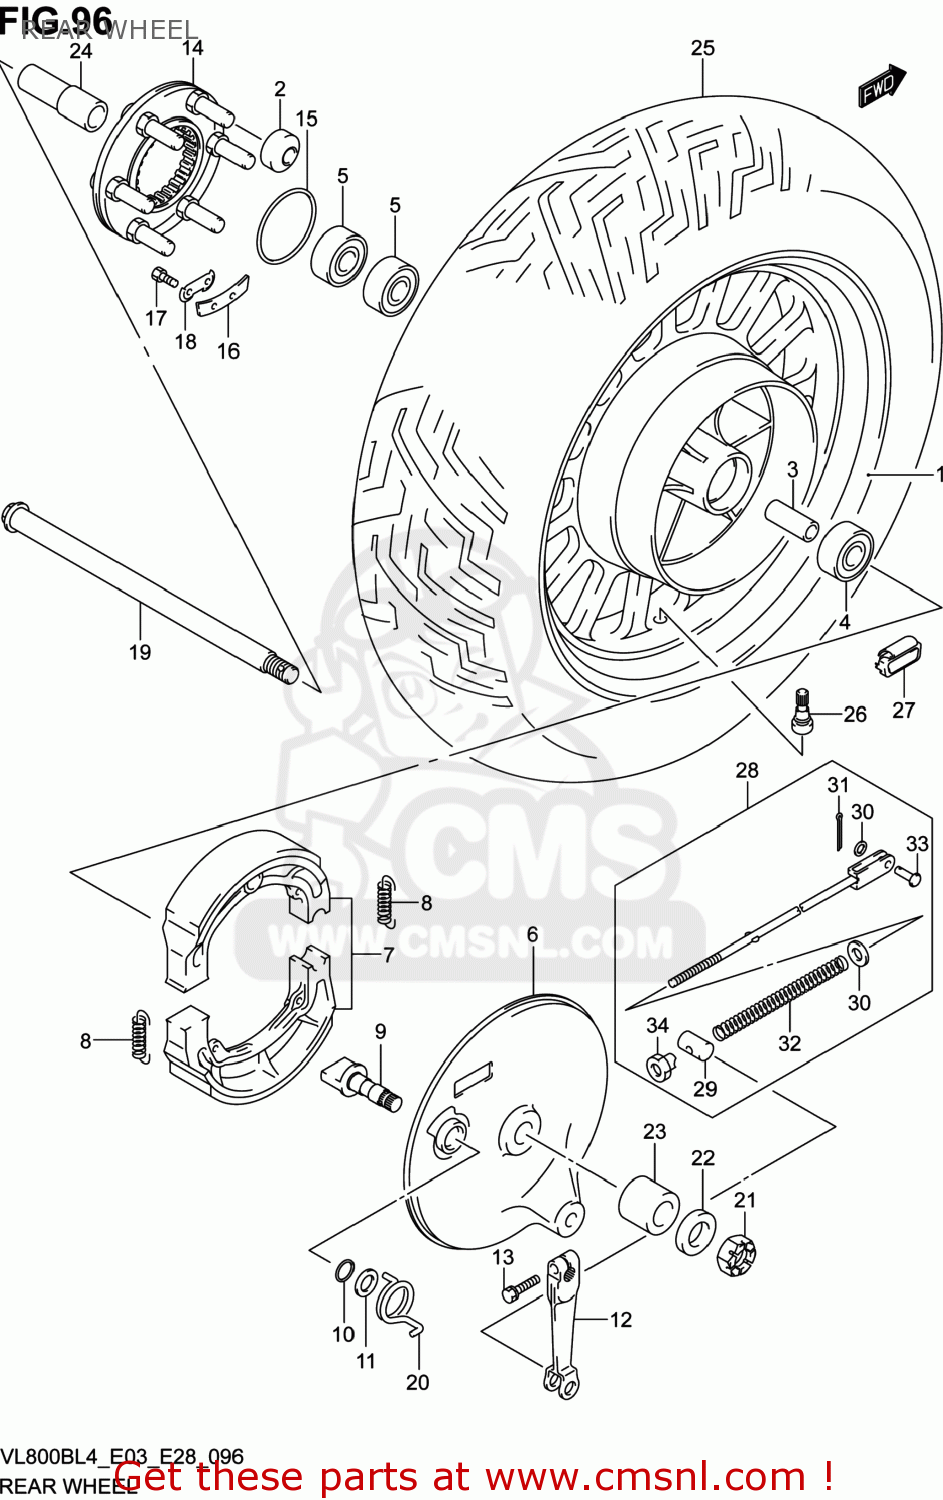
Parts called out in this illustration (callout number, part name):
1	WHEEL,RR(15M/CXMT4.00)
2	BUSH
3	SPACER(17.3X25X99)
4	BEARING
5	BEARING
6	PANEL,RR BRAKE ANCHOR
7	SHOE SET,BRAKE (NAS)
8	SPRING,BRAKE SHOE
9	CAM,RR BRAKE
10	O RING(D:2.4,ID:14.8)
11	WASHER(15.5X24X1.6)
12	LEVER,RR BRAKE CAM
13	BOLT
14	JOINT ASSY,RR HUB DRIVEN
15	O RING(D:2.1,ID:65)
16	WASHER,THRUST(T:1.6)
17	BOLT(6X16)
18	WASHER
19	AXLE,RR
20	SPRING
21	NUT
22	WASHER(17X30X3.2)
23	SPACER,RR AXLE,R
24	SPACER,RR AXLE,L
25	TIRE,RR(170/80 15M/C 77H)
26	VALVE ASSY,WHEEL RIM(TR412)
27	BALANCER,WHEEL NO.1
28	ROD ASSY,RR BRAKE
29	PIN(13X18)
30	WASHER
31	PIN
32	SPRING
33	PIN(L:13.5)
34	NUT
